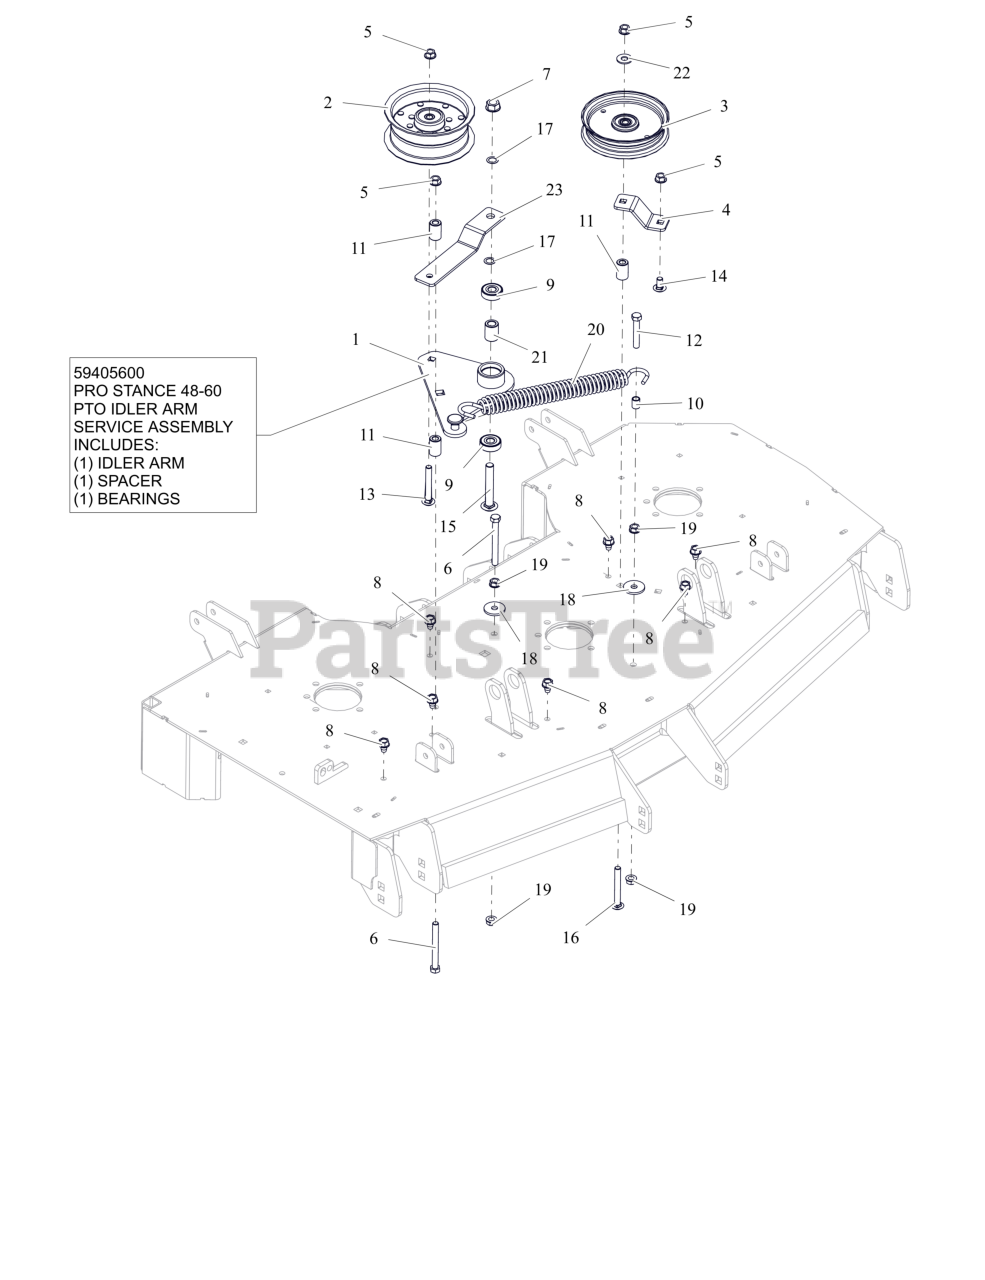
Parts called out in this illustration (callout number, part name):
1	WLDMT, PTO IDLER ARM
1	PTO IDLER ASSEMBLY
2	PULLEY, FLAT 5.00X2.36X.375
3	IDLER- FLAT - 5.00" X .75"
4	PTO FIXED IDLER MTG BRKT -RED
5	NUT-LK-CTR-FLG .375-16 GF ZCC
6	BLT, HEX .38-16X3.50 G5 ZCC
7	NUT-LK-CTR-FLG .500-13 GG ZCC
8	SCR,TAP .375-16X.50 HWH TR ZCC
9	BRG-BALL .500X1.38X.437
10	SPCR, SLV .385X.500X.652
11	BUSHING, SLV .380X.750X1.190
12	BLT,HEX .38-16X2.25 G5 ZCC
13	BLT, RHSN .38-16X2.75 G5 ZCC
14	BTL,RHSSN .375-16 X 0.75 G5 FPB
15	BTL,RHSSN .500-13 X 3.25 G5 ZCC
16	BTL,RHSSN .375-16 X 3 G5 ZCC
17	WASHER, .500X.750X.020 THRUST
18	WSHR,FLT .406X1.375X.135 ZCC
19	NUT, SPNLK-FLG .38-16 G5 ZCC
20	SPRING, EXTENSION
21	SPACER .510 X .867 X 1.1485
22	WSHR,FLT .438X1.00X.083 ZCC
23	BRKT, PROSTANCE PTO IDLER (RED)
